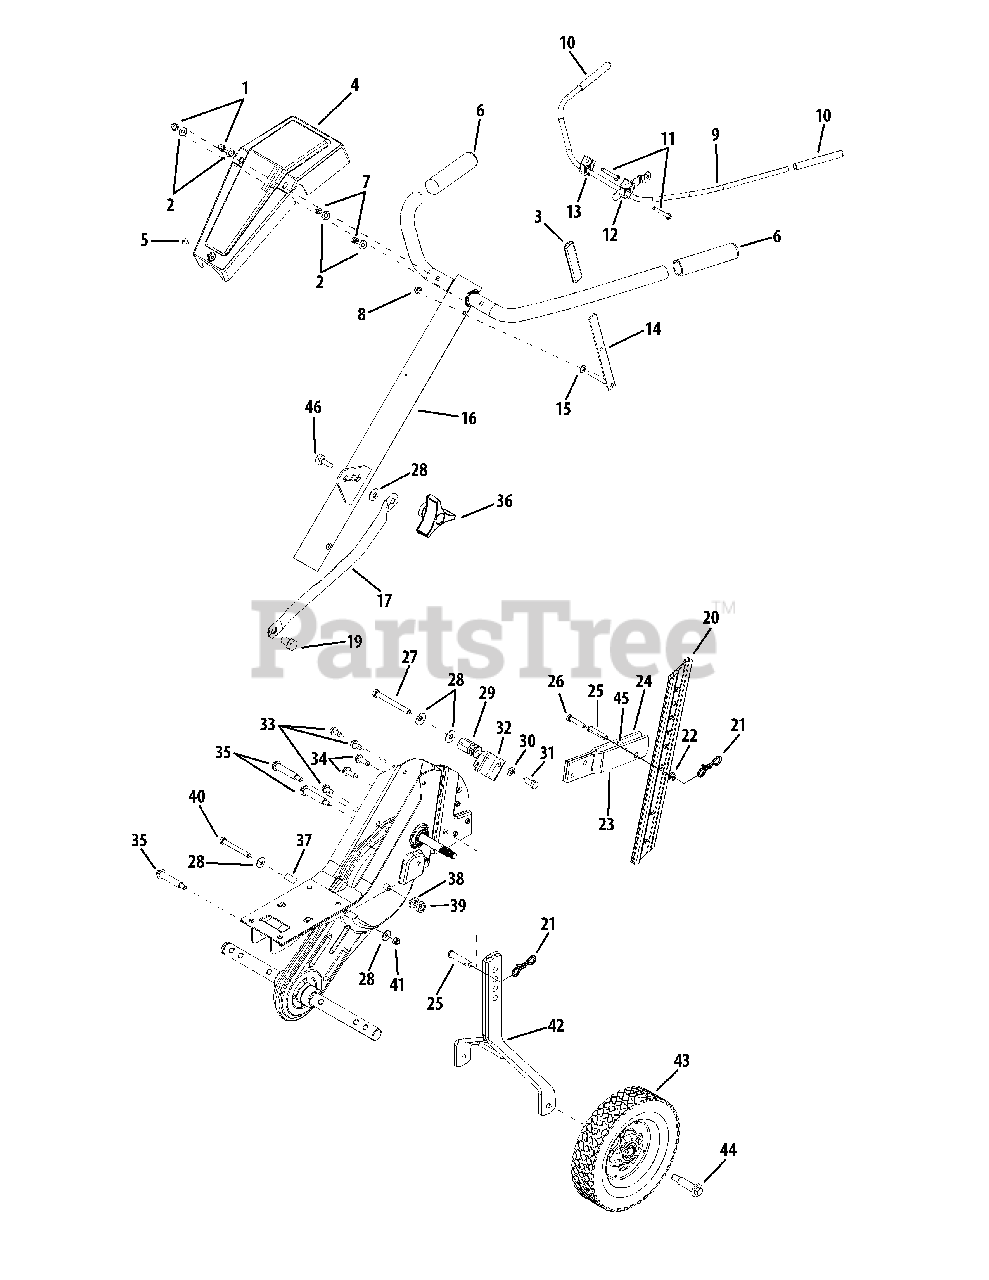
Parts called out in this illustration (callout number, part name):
1	Acorn Lock Nut 1/4-20
2	Flat Washer .266 ID x .625 OD
3	Reverse Handle Grip
4	Handle cover (w/o throttle)
5	Truss Mach Tapp Scr #10 X .50
7	Hex Nut 1/4-20 Gr. 5
8	Cap Speed Nut 5/16" Rod
9	Clutch Handle Assembly
10	Grip-Clutch
11	Screw - .250-20 X 2.25 Hex Wash
12	Clutch Handle Holder
13	Flat Washer .385 ID x .62 OD x .06
14	Reverse Handle Ass’y
15	Flat Washer .344 ID x .625 OD x .063
16	Handle Ass’y Complete
17	Handle Brace
19	Hex Bolt 1/2-20
20	Depth Bar
21	Bow Tie Cotter Pin
22	Flange Locknut 5/16-18 Gr. F, Nylon
23	Tail Piece Brkt. (LH)
24	Tail Piece Brkt. (RH)
25	Clevis Pin 3/8 Dia
26	Hex Bolt 5/16-18 x 1,50" Lg. Gr. 5
27	Hex Screw 5/16-18 X 3.00
28	Cupped Washer .345 ID x .88 OD x .060
29	Hex Nut Special
30	L-Wash 5/16 ID
31	Hex Bolt 5/16-18 x .75" Lg. Gr. 5
32	Cable Guide Bracket
33	Self-tapping Screw 5/16-18 x .625
34	Hex Wash Hd Tapp Scr 5/16-18 x 1.00
35	Shoulder Bolt 5/16-18
36	Handle Knob
37	Spacer
38	Lockwasher 7/16 ID
39	Hex Jam Nut 7/16-20
40	Hex Scr 5/16-18 x 2.75
41	Hex Ins. L-Nut 5/16-18
42	Wheel Hanger Brkt. Ass’y
43	Wheel Assembly 8 x 1.75
44	Shoulder Screw .496 ID x 1.445 OD
45	Spacer .32" ID x .75" OD
46	Carriage Bolt 5/16-18 x 1.00
47	Cupped Washer
